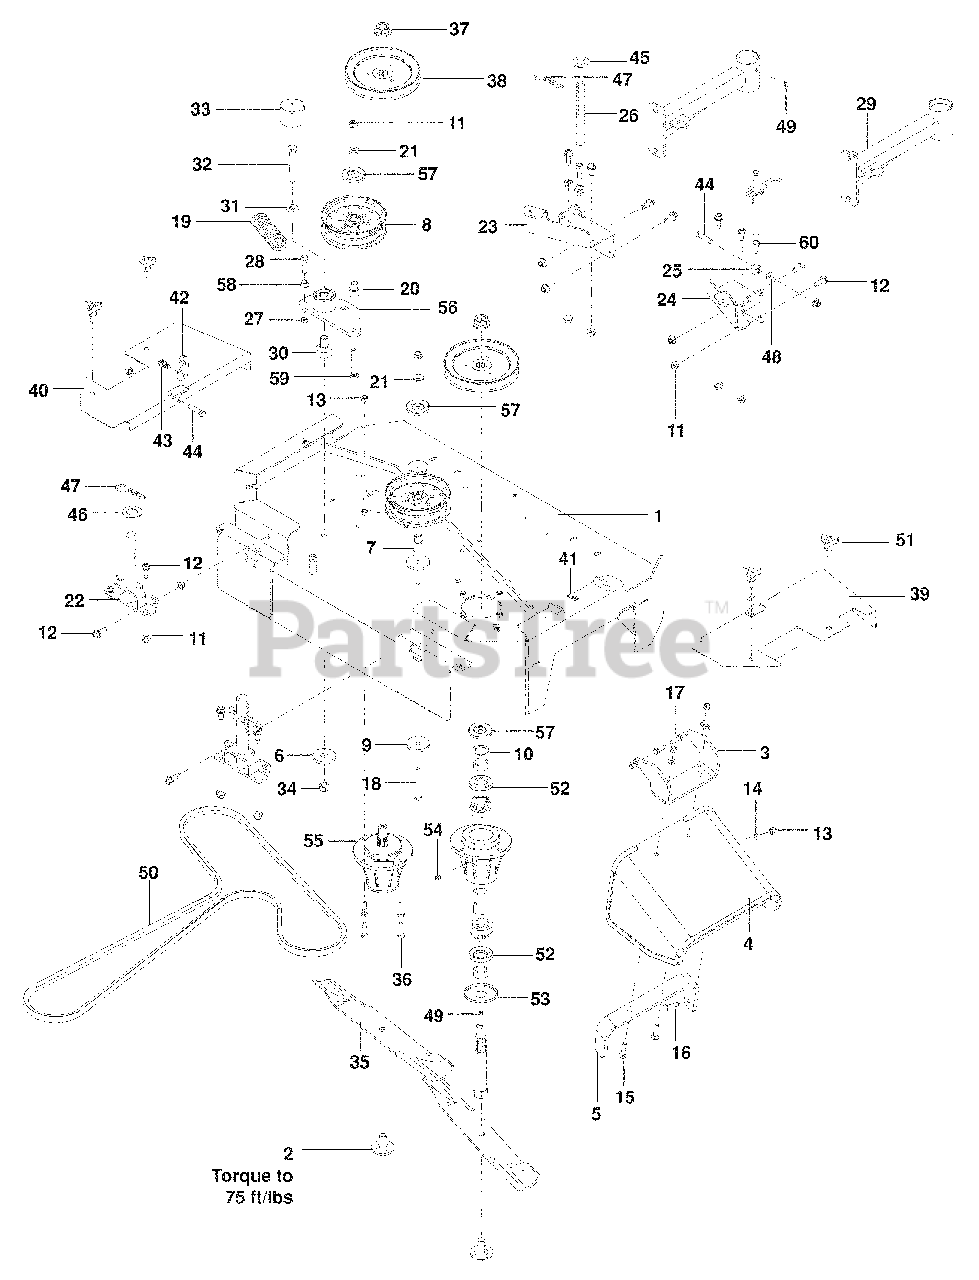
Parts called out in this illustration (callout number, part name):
1	CUTTER DECK w/ DECALS
2	BLADE BOLT w/ WASHER
3	HINGE, CHUTE
5	REINFORCEMENT, BRKT
6	SUPPORT WASHER
7	BUSHING IDLER
8	PULLEY, IDLER
9	WASHER, HEAVY
11	NUT 3/8-16 HEX FLG NYLOC
12	BOLT 3/8-16 x 1 THD FRM
13	NUT 5/16-18 HEX NYLOC
14	WASHER 5/16 SAE FLAT
15	RHSNB 5/16-18 x 1½
16	RHSNB 5/16-18 x 1¼
17	HCS 5/16-18 x 1
18	HCS 3/8-16 x 3
20	BUSHING, IDLER
21	WASHER 3/8 THICK
23	SUPPORT, FRONT LH
24	SUPPORT, FRONT RH
25	ROD END 3/8-24 RH
27	NUT 3/8-16 HEX JAM
28	HCS 3/8-16 x 1½ GR 8
29	SUPPORT, CASTER
30	PIVOT, BEARING
31	WASHER ½" BELLEVILLE
32	HCS ½-13 x 3¼
33	CAP, VINYL
34	NUT ½ HEX NYLOC
35	BLADE, 18"
36	HCS 5/16-18 x 1¼
37	NUT ¾-16 FLANGE
41	RETAINER, U TYPE
43	SPRING, COMPRESSION
44	HCS 3/8-16 x 1½
45	WASHER ¾ FLAT SAE
47	HAIR PIN COTTER 3"
48	WASHER 3/8 x ¾
50	BELT, DECK
51	KNOB w/ STUD
52	SHAFT SEAL
53	BOTTOM DUST CAP
54	GREASE POPPET
55	HOUSING ASSY
56	ARM, IDLER w/ BEARINGS
57	SHIELD, DUST
58	NUT 3/8-16 HEX WHIZLK
59	RHSNB 3/8-16 x 2¾
60	NUT 3/8-24 HEX GR 2
